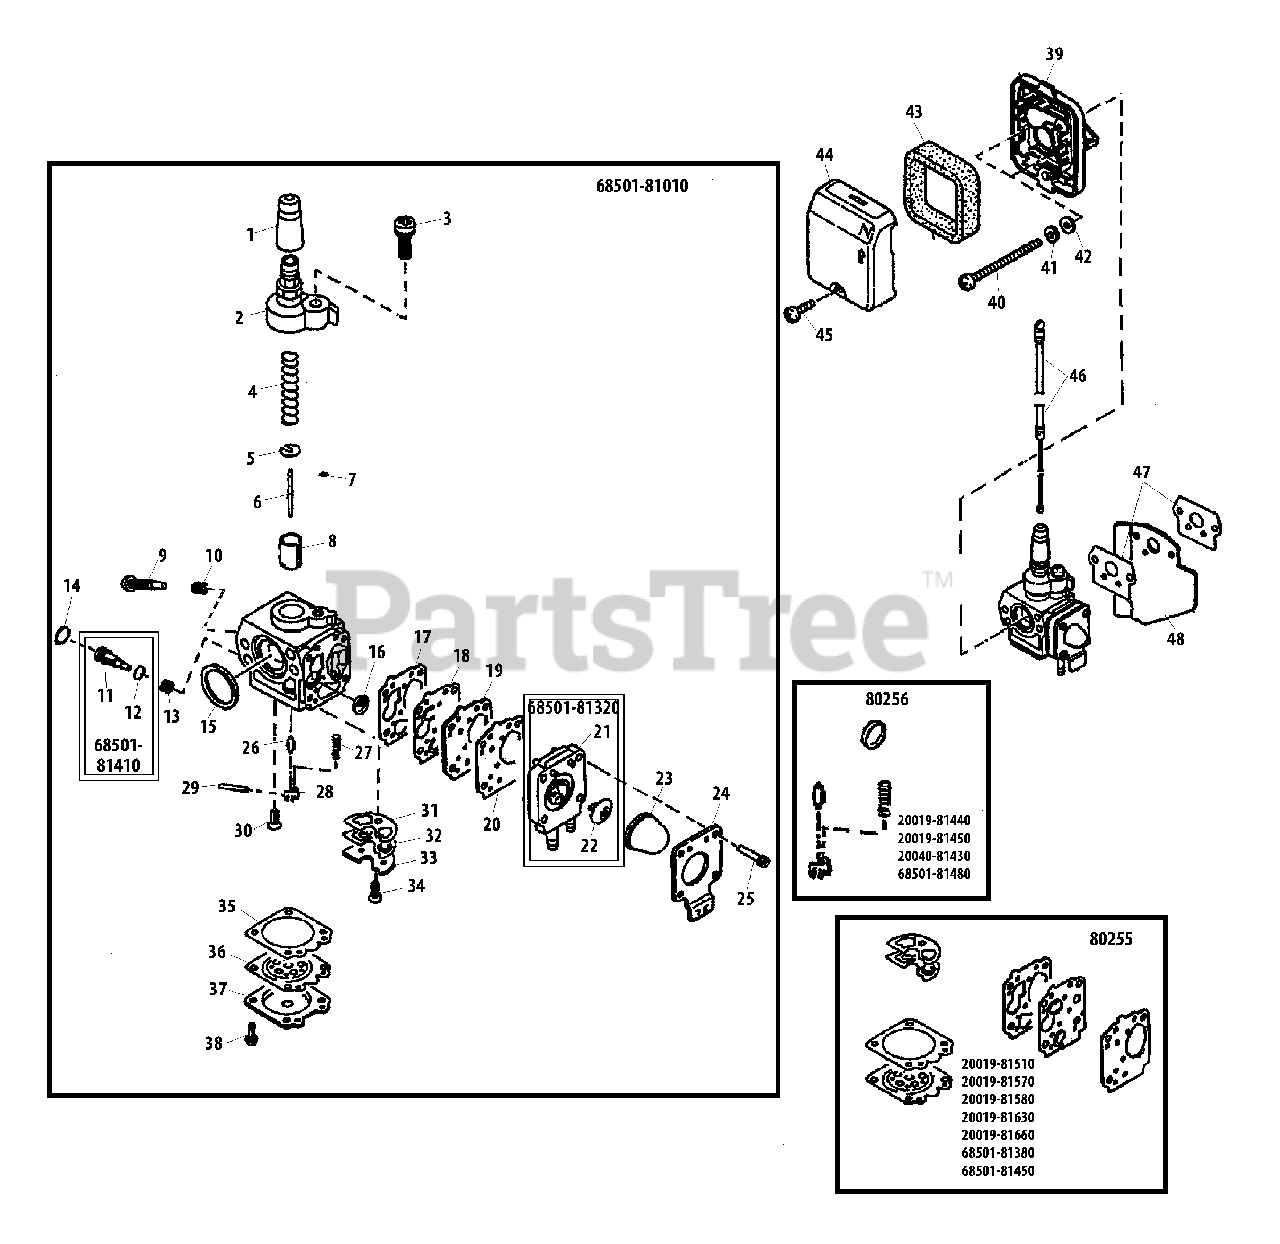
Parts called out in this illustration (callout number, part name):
1	GROMMET
2	CAP, CARBURETOR
3	SCREW
4	SPRING
5	RETAINER
6	JET, NEEDLE
7	JET, NEEDLE
8	SLIDE VALVE
9	SCREW, IDLE ADJUST
10	SPRING
11	SCREW, ADJUST
14	PLATE
15	SEAL
16	SCREEN, SPARK ARRESTOR
17	GASKET, PUMP
18	DIAPHRAGM, PUMP
19	PLATE, PUMP
20	GASKET, PUMP
21	COVER, PUMP
22	VALVE
23	BULB, PURGE
24	COVER, PUMP
25	SCREW - 3X14
26	VALVE, INLET NEEDLE
27	SPRING
28	LEVER, METERING
29	PIN, METERING LEVER
30	SCREW, METERING LEVER PIN
31	GASKET
32	VALVE, CHECK
33	PLATE
34	SCREW, METERING LEVER PIN
35	GASKET, METERING
36	DIAPHRAGM, METERING
37	COVER, DIAPHRAGM
38	SCREW
39	CASE, AIR FILTER
40	SCREW
41	LOCKWASHER - 5
42	WASHER - 5
43	FILTER, AIR
44	COVER, AIR FILTER
45	SCREW - 5X16
46	CABLE, THROTTLE
47	GASKET, PUMP
48	GASKET, INTAKE
68501-81010	CARBURETOR
68501-81320	BASE, PURGE
68501-81410	SCREW, ADJUST
80255	DIAPHRAGM/GASKET KIT
80256	REPAIR KIT
